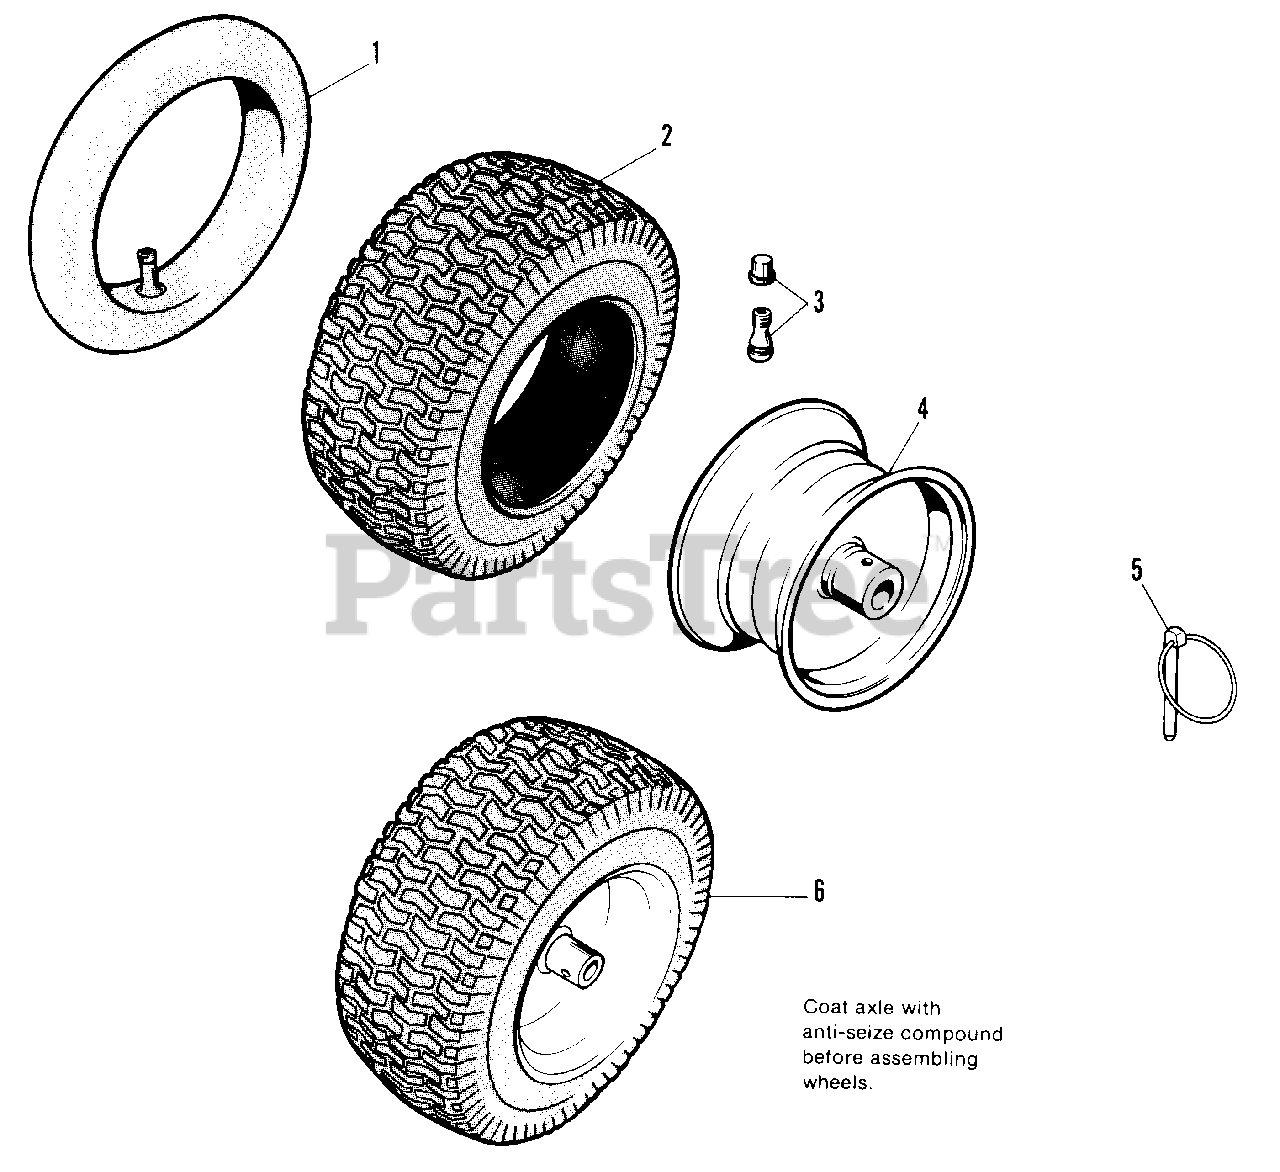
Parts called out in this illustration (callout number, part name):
1	TUBE (Service Only) 4.80/4.00-8
2	TIRE, 4.80/4.00-8 (All models except 1691707 & 1691708)
2	TIRE, "Snow Hog" (1691707 & 1691708 only)
3	VALVE STEM & CAP
4	WHEEL & HUB ASSY.
6	WHEEL & TIRE ASSY. (All models except 1691707 & 1691708)
6	WHEEL & TIRE ASSY. (1691707 & 1691708 only)
